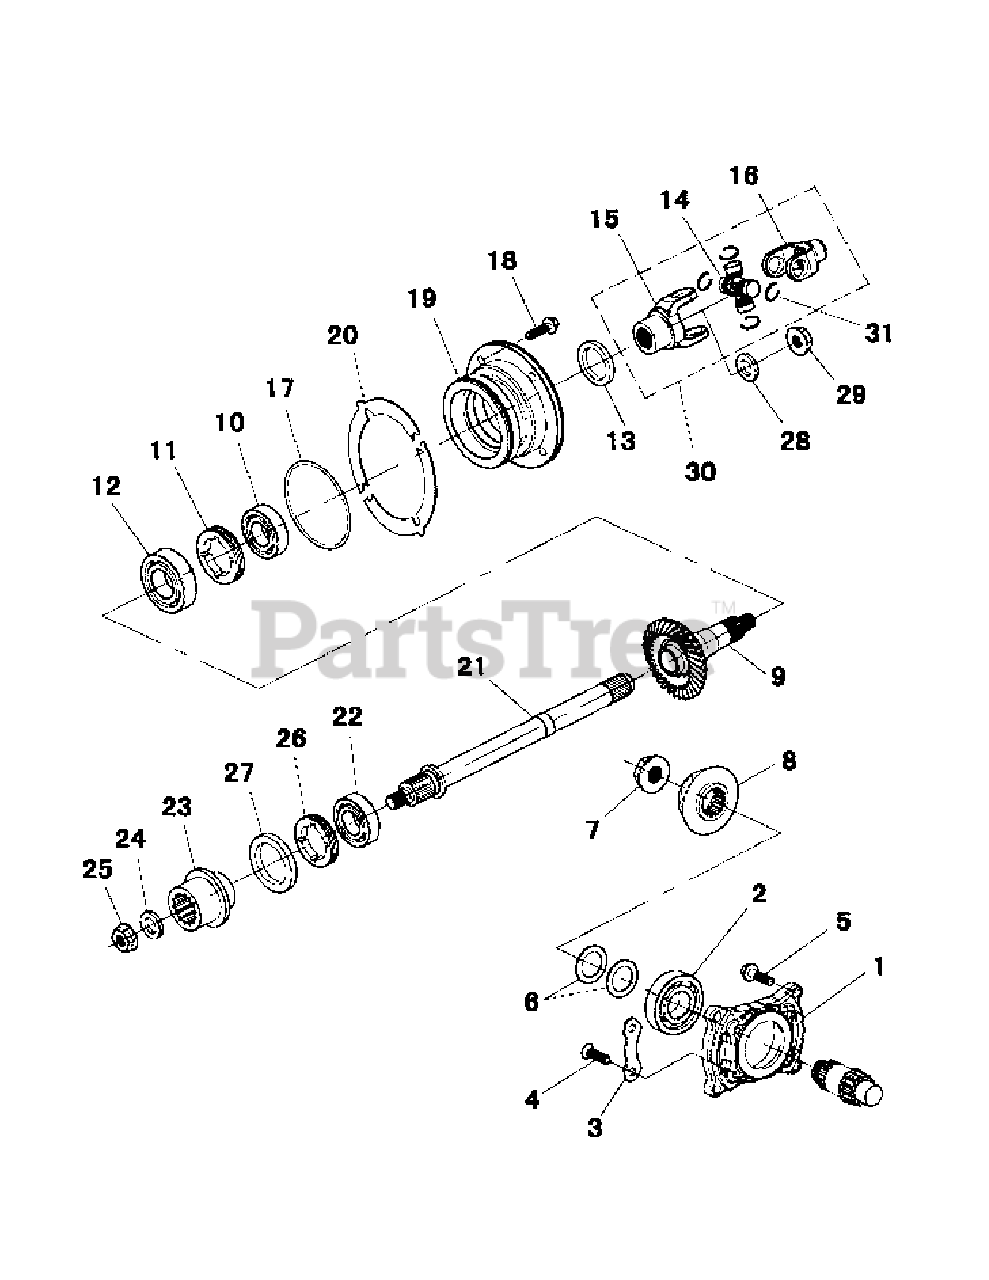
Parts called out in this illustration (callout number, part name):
1	Bearing Seat-Output
3	Press Plate Bearin
5	Flangebolt M6X30
8	Gear Wheel-Driver
9	Gear Wheel-Driven
11	Locked Ring-M60
14	Crossing
15	Universal Joint A
16	Universal Joint B
17	O-Ring 88X2.8
19	Output Shaft-Beari
20	Washer
23	Coupling-Flange
26	Lock Ring-M55
27	Seal
30	Universal Join tComp
31	Clip
